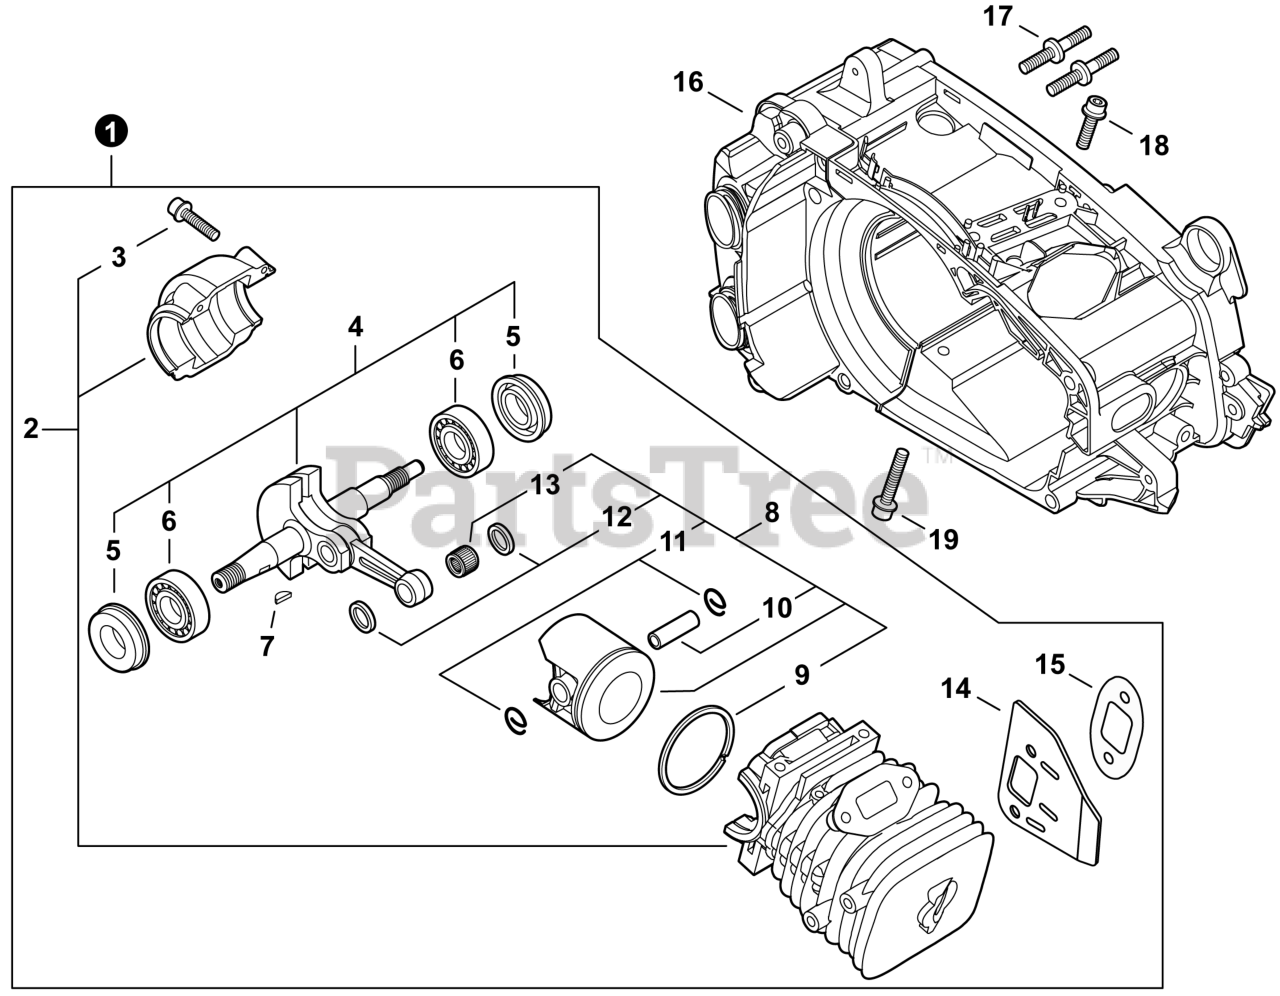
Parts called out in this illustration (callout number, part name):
1	SHORT BLOCK
2	CRANKCASE SET
3	BOLT, TORX 5x20
4	CRANKSHAFT ASSY
5	SEAL, OIL 12
6	BEARING, BALL 6201
7	KEY, WOODRUFF
8	PISTON KIT
9	RING, PISTON
10	PIN, PISTON
11	RING, SNAP
12	WASHER, THRUST
13	BEARING, NEEDLE 8
14	HEAT SHIELD, EXHAUST
15	GASKET, EXHAUST
16	COVER, ENGINE
17	STUD, GUIDE BAR
18	BOLT, TORX 5x20
19	BOLT, TORX 5x30
